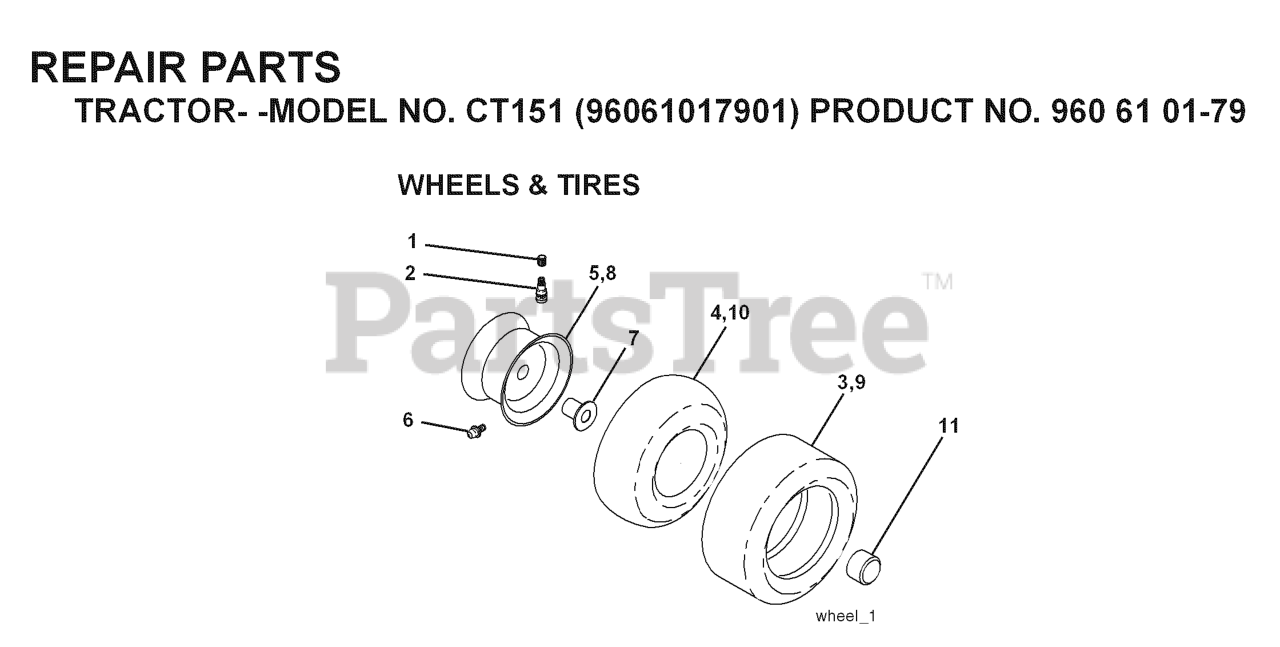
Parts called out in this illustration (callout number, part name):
2	VALVE STEM LT
3	TIRE HEAVY DUTY
4	TUBE.5.3/4.5/6
5	RIM ASM 6" FRONT SILVER
6	FITTING LT
7	BEARING T
8	RIM ASM 8" REAR SILVER
9	TIRE HEAVY DUTY
10	TUBE
11	CAP, AXLE BLK
